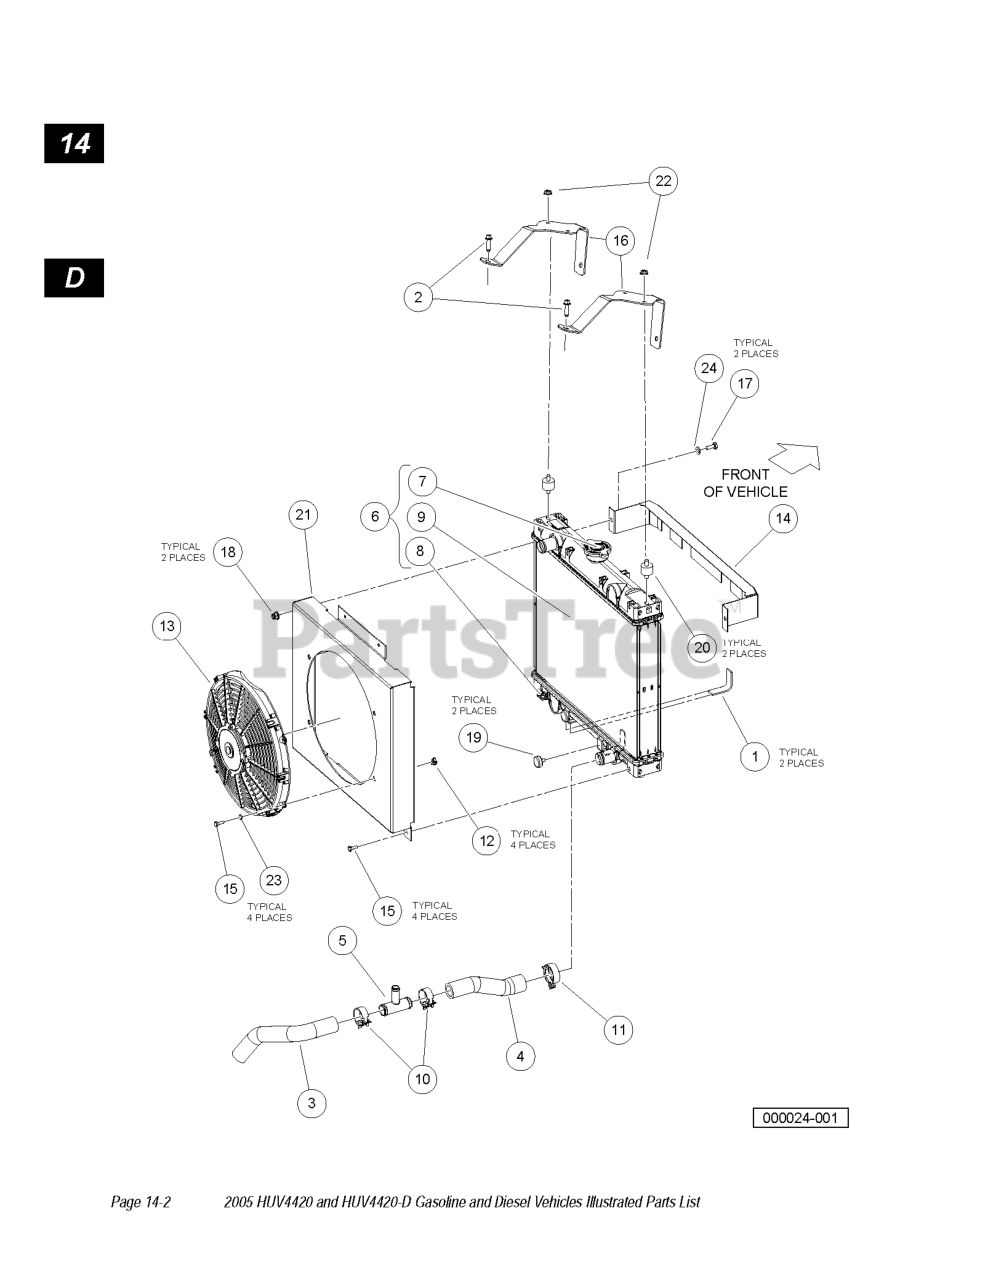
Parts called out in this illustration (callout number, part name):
1	BOX INS.BULK
2	SCREW-M8 X 1.25 30, TRI, HX F
3	HOSE, COOLANT LOWER PIPE
4	HOSE, COOLANT LOWER RAD
5	TEE, COOLANT FILL
6	EXCHANGER, ENGINE COOLANT
7	CAP, RADIATOR, NON PRESSURE
8	DRAIN COCK, RADIATOR
10	CLAMP, HOSE, CTB 35MM
11	CLAMP, HOSE, CTB 38MM
12	NUT, SELF RETAINING
13	FAN, COOLING 12 IN ELECT
14	GUARD, RADIATOR-TOP
15	BOLT, M6 X 1 X 16 LOCTITE
16	BRACKET, UPPER RADIATOR MOUNT
17	BOLT, M8 X 1.25 X 20
18	LOCK NUT, FLG M8 X 1.25 NYLON
19	BUMPER, 13MM STUD
20	ISOLATOR, TWIN STUD, RADIATOR
21	SHROUD, RADIATOR FAN
22	NUT, M8-1.25 FLANGED HEX
23	WASHER, M6
24	WASHER, M8 HARD
